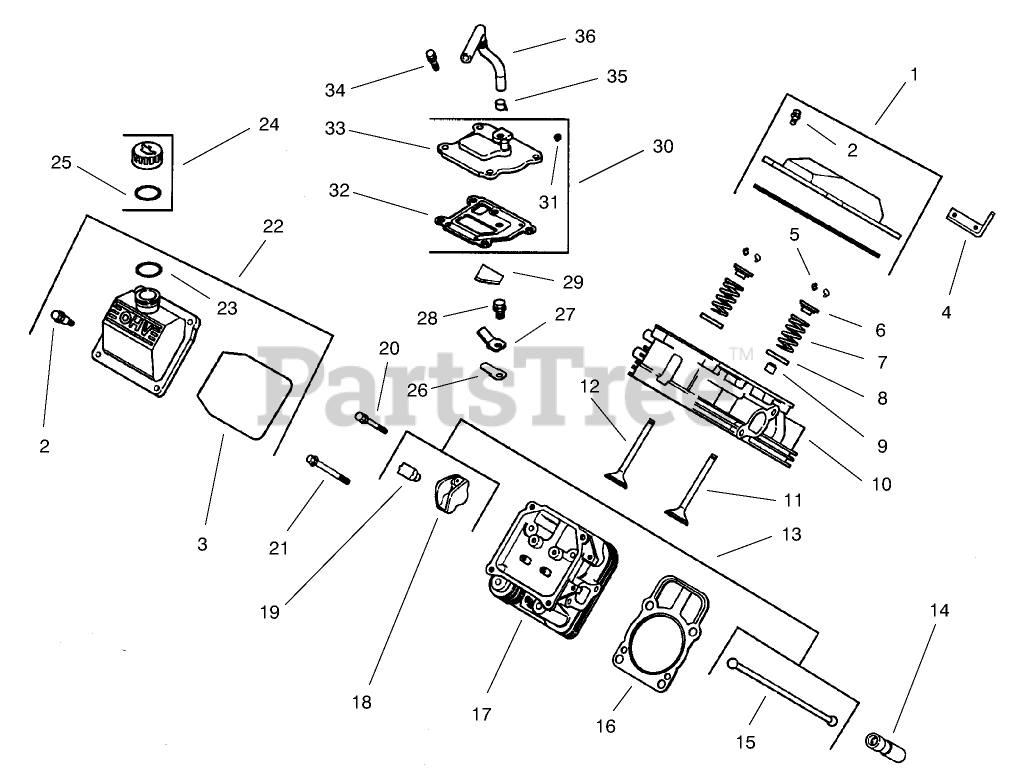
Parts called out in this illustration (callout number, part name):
1	Kit-Valve Cover (Incl. Ref. #2 3)
2	Screw-Shoulder
3	O-Ring
4	Strap-Lifting
5	Kit-Retainer
6	Cap-Valve Spring
7	Spring-Valve
8	Retainer-Spring
9	Seal-Valve Stem
10	Head Assembly (#1 Cylinder)
11	Valve-Intake
12	Valve-Exhaust
13	Kit-Valve Incl 1726-27
14	Lifter-Valve
15	Rod-Push
16	Gasket-Cylinder Head
17	Head-Assembly (#2 Cylinder)
18	Arm-Rocker
19	Pivot-Arm, Rocker
20	Screw
21	Screw
22	Kit-Valve Cover (Incl. Ref. #2-4)
23	ORing
24	Kit-Oil Fill Cap (Incl. Ref. #7)
25	ORing
26	Reed
27	Retainer-Reed
28	Screw
29	Filter-Breather
30	Kit,-Breather
31	Plug
32	Gasket-Breather
33	Cover-Breather
34	Screw
35	Clamp
36	Hose-Breather
